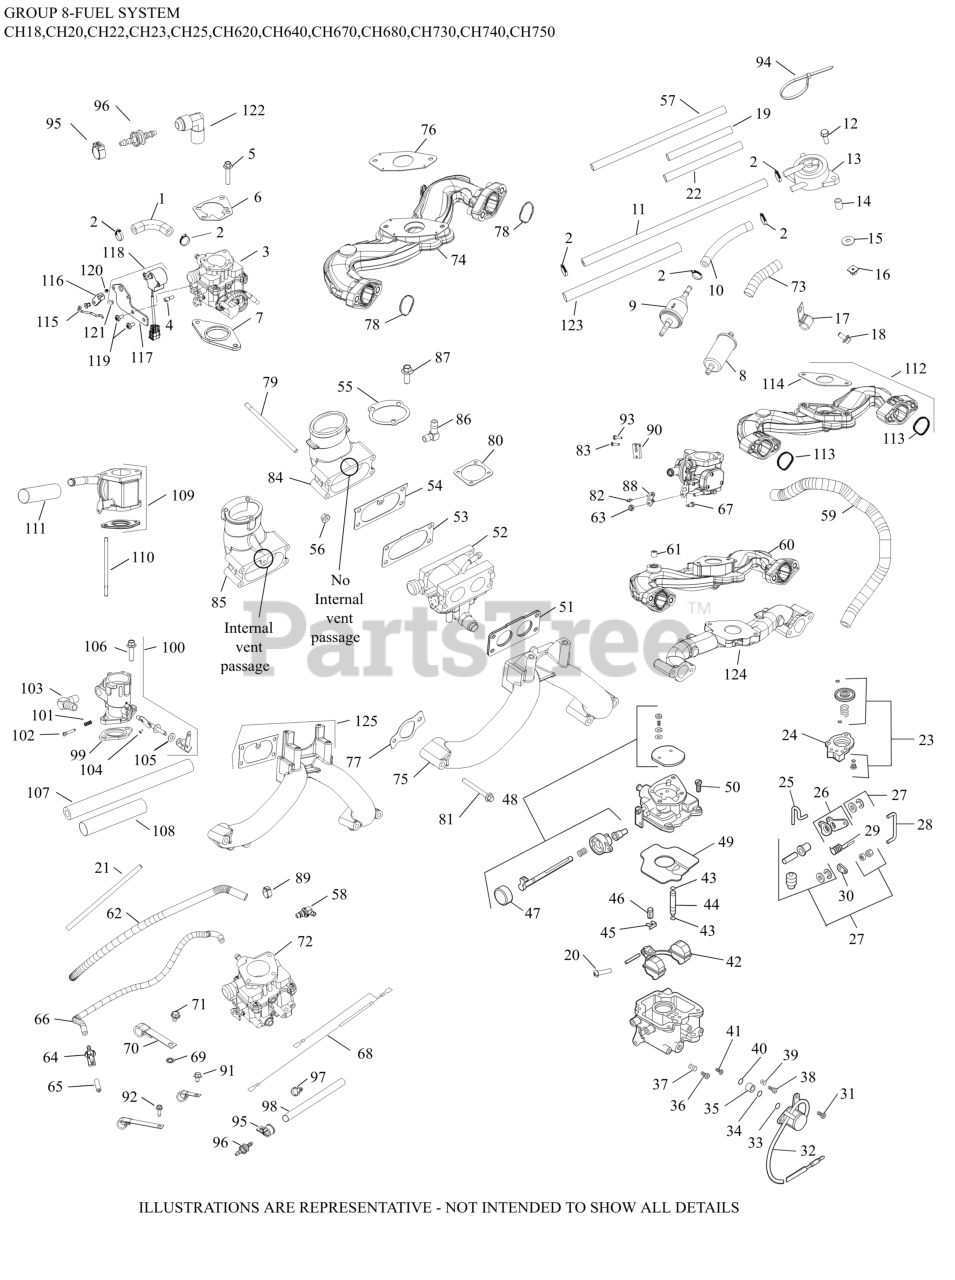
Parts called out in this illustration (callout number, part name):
1	HOSE,LW PERM.FUEL 24.00"-USE 25 111 81-S
2	CLAMP, HOSE (KM)-USE 25 237 31-S
3	KIT,CARB (KEIHIN) W/GASKETS-(#24853313S)
5	SCREW, FLG M6X1.0X30
7	GASKET, CARBURETOR
9	FILTER, FUEL
23	KIT, REPAIR ACC PUMP
27	KIT, REPAIR-ACC PUMP SEAL
32	KIT, SOLENOID
42	KIT, REPAIR FLOAT
48	KIT, REPAIR CHOKE
62	SLEEVE, ANTI-ABRASION
77	GASKET, INTAKE MANIFOLD-USE 24 041 79-S
124	MANIFOLD, METAL INTAKE
NI	KIT, HIGH ALT (Above 8,000 FT)
NI	KIT,HIGH ALTITUDE (4,000 - 8,000 FT)
NI	KIT, REPAIR CARBURETOR
